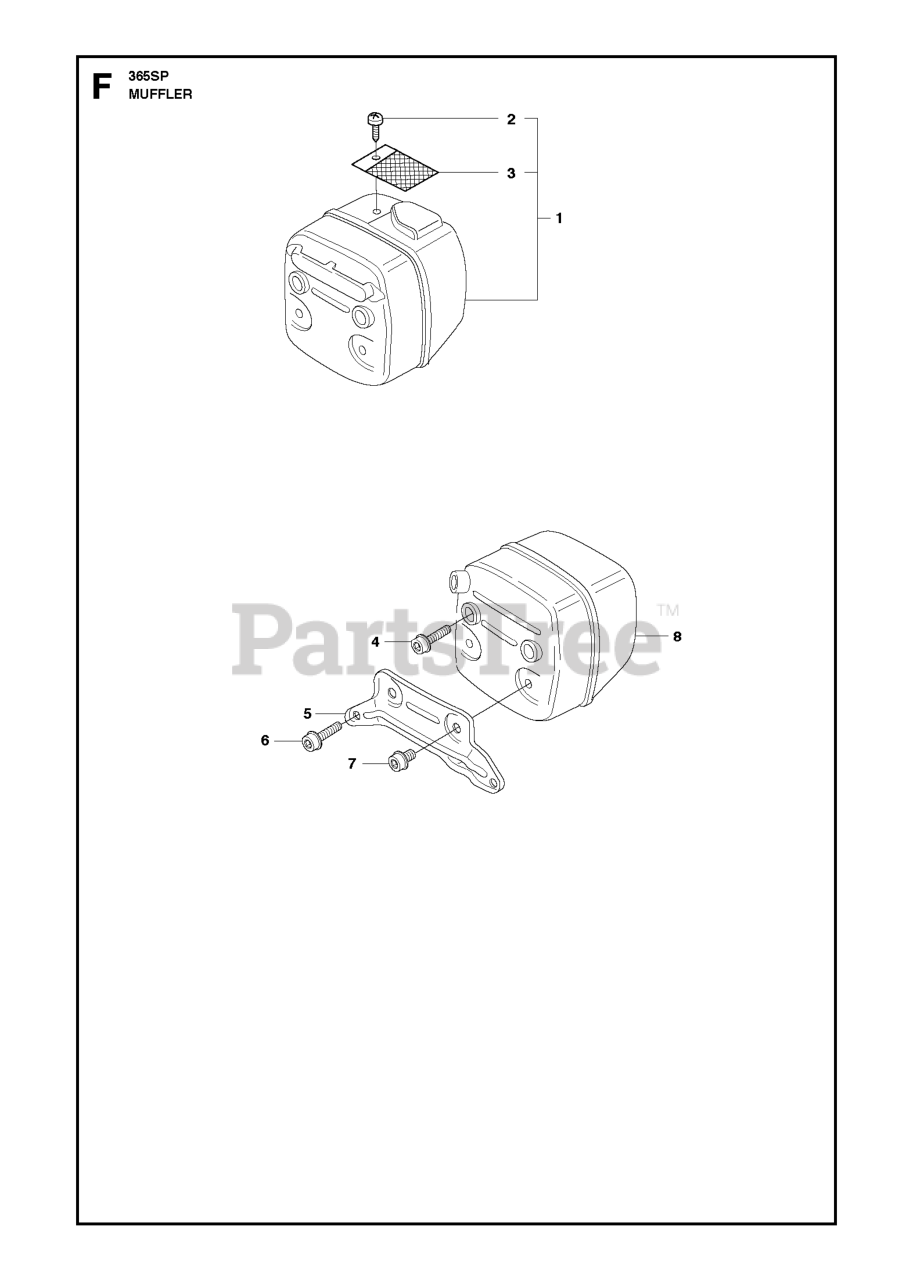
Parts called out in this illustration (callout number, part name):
1	MUFFLER
4	SCREW ITXSCM M6X20 T27 12.9 T
7	SCREW ITXSCFM M5X8 T27 10.9 Z
8	MUFFLER ASSY
